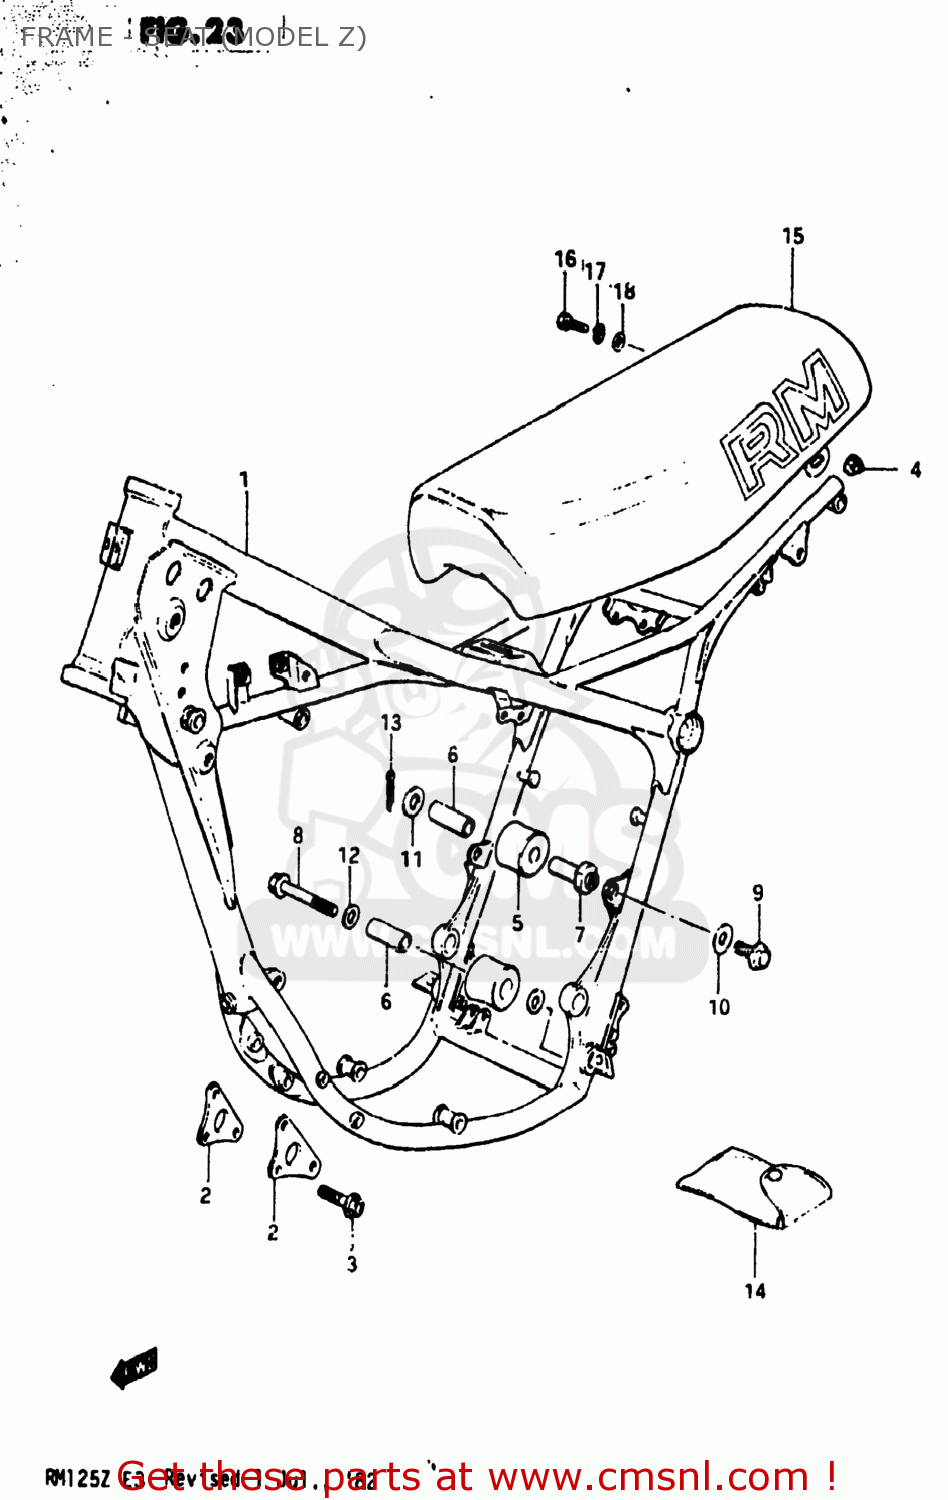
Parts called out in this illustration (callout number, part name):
1	FRAME
2	PLATE,ENGINE MOUNTING
3	BOLT(8X36)
4	PLUG(OD:17)
5	ROLLER,CHAIN LENGTH CONTROL
6	SPACER,CHAIN LENGTH ROLLER
7	BOSS,CHAIN LENGTH ROLL
8	BOLT(8X45)
9	BOLT
10	WASHER
11	WASHER
12	WASHER
13	PIN 25X20
14	TOOL SET
15	SEAT ASSEMBLY
16	BOLT
17	WASHER,LOCK,8.
18	WASHER (8.5X20X2.6)
